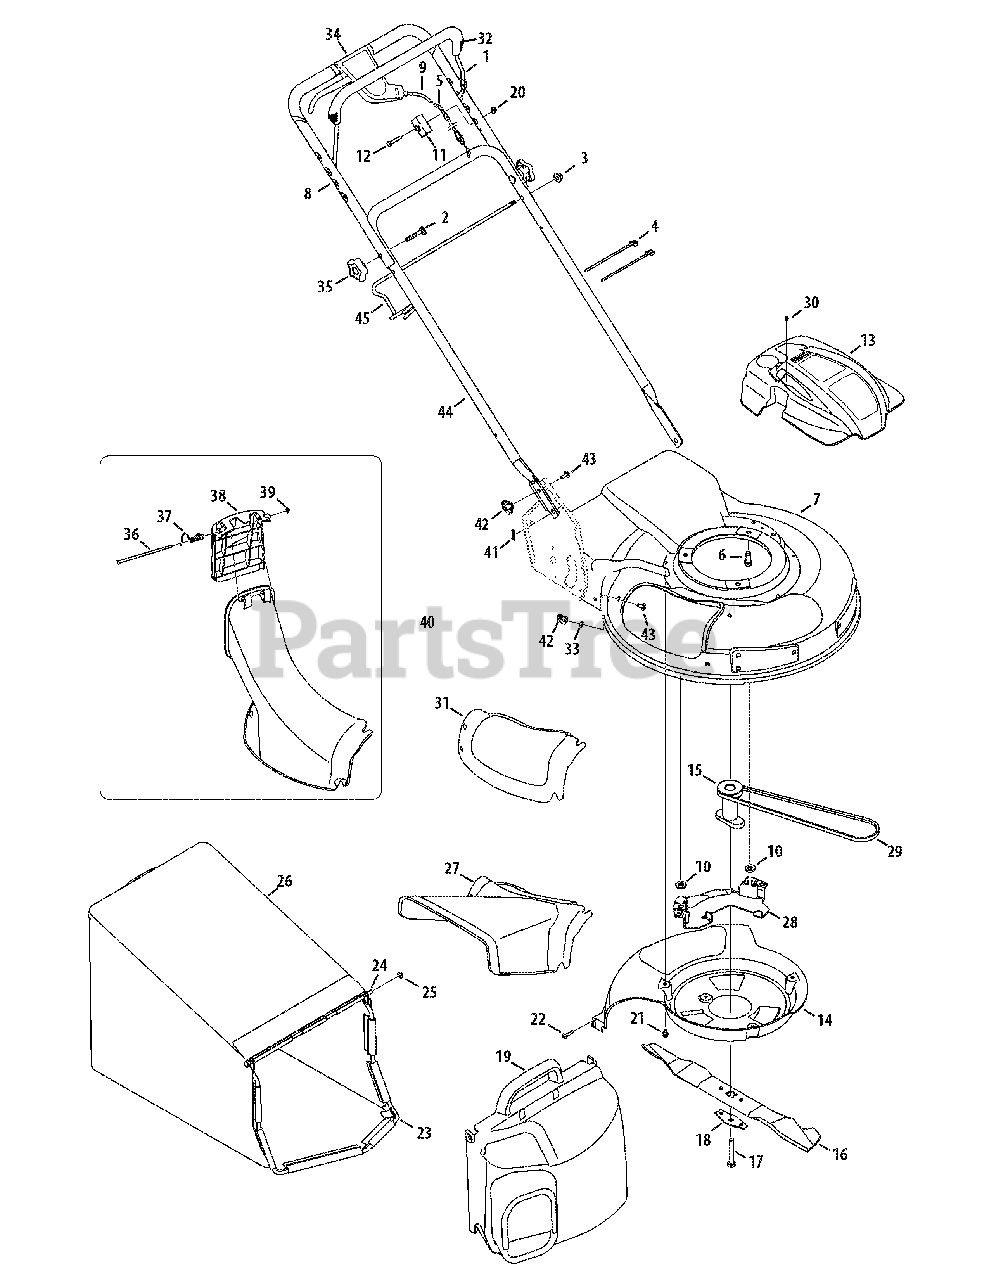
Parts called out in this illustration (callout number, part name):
1	Blade Control
2	Carriage Bolt 5/16-18 x 2
3	Flange Lock Nut, 5/16-18
4	Cable Tie
5	Control Cable
6	TT Screw, 3/8-16 x 1.00
9	Drive Cable
10	Washer, Flat, .407 x .812 x .135
11	Control Cable Mount
12	Screw, 1/4-20 x 1.50
13	Engine Shroud
14	Rear Baffle
15	Blade Adapter
16	21-inch Mulching Blade
17	HH Cap Screw, 3/8-24 x 2.50
18	Bell Blade Spacer
19	Grass Bag Cover Assembly
20	Flange Lock Nut 1/4-20
21	TT Screw 1/4-20 x .375
22	HL Screw 1/4-15 x .75
23	Grass Bag Frame
24	Grass Bag Pivot Rod
25	Cap Speed Nut
26	Grass Bag Assembly
27	Side Discharge Chute
28	Belt Keeper
30	Screw, #12-16 x 1.00
31	Mulch Cover
32	Bail Cover
34	Drive Control Assembly
35	Star Knob
36	Chute Door Pivot Rod
37	Torsion Spring
38	Top Discharge Door Chute
40	Top Discharge Chute Assembly
41	Cotter Pin
42	Wing Nut
43	Carriage Screw 1/4-20 x .75
45	Grass Bag Support Rod
